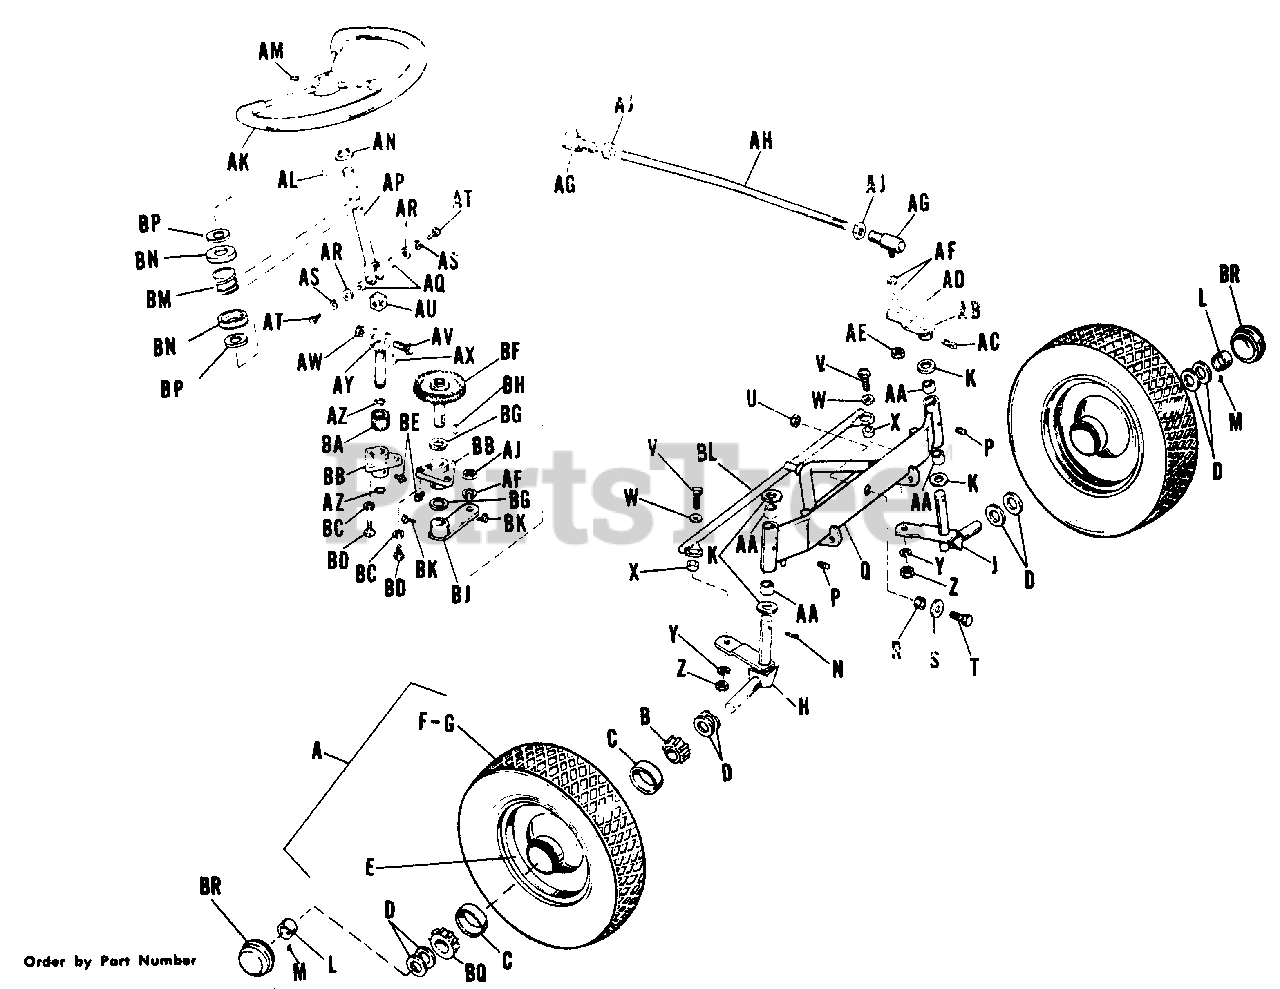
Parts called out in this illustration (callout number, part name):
A	Wheel and Tire Assembly
B	Cone, Bearing, w/seal
C	Bearing Cup,
E	Wheel w/bearing cup
F	Tire, 4.80/4.00
G	Tube, 4.00-8
H	Spindle Assembly, R.H.
J	Spindle Assembly, L.H.
L	Collar, Set
M	Screw, Set, Cup Point, Socket Head, 5/16"-18 N.C. x 1/4" lg.
N	Pin, Cotter, 3/16" x 1-1/2" lg.
P	Fitting, Grease
Q	Axle Assembly, Front
S	Washer, Plain, 1/2"
T	Screw, Cap, Hex., 1/2"-13 N.C. x 1-1/2" lg.
U	Nut, Hex., Full, Lock, 1/2"-13 N.C.
V	Screw, Cap, Hex., 3/8"-16 N.C. x 1-1/4" lg.
W	Washer, Plain, 3/8"
Y	Washer, Lock, 3/8"
Z	Nut, Hex., Full, 3/8"-16 N.C.
AB	Arm Assembly, Steering, L.H.
AC	Screw, Set, Cup Point, Square Head, 5/16"-18 N.C.x 1/2" lg.
AD	Key, Hi-Pro
AE	Nut, Hex., Full 1/2"-20 N.C.
AF	Washer, Lock, 1/2"
AG	Joint, Ball
AJ	Nut, Jam, 1/2"-20 N.F.
AK	Wheel, Steering
AL	Key, Woodruff #9
AM	Screw, Set, Cup Point, Socket Head, 5/16"-18 N.C. x 5/16" lg.
AP	Shaft Assembly, Steering
AR	Washer, Plain, 3/8"
AS	Washer, Lock, 3/8"
AT	Screw, Cap, Hex., 3/8"-16 N.C. x 3/4" lg.
AU	Pin, Universal Joint
AV	Screw, Cap, Hex., Head, Special
AW	Nut, Lock, Full, Hex., 5/16"-18 N.C.
AX	Key, Woodruff #9
AY	Shaft Assembly, Steer, Pin
AZ	Ring, Retaining
BB	Bearing, Steering Gear
BC	Washer, Lock, 5/16"
BD	Screw, Cap, Hex., 5/16"-18 N.C.
BE	Fitting, Grease, #1641
BF	Gear Assembly, Steering
BH	Key, Woodruff #9
BJ	Arm Assembly, Steering
BK	Screw, Set, Cup Point, Square Head, 5/16"-18 N.C. x 1/2" lg.
BL	Drag Link
BM	Spring, Compression
BN	Cup, Spring
BQ	Bearing, Outside.
BR	Cap, Hub.
